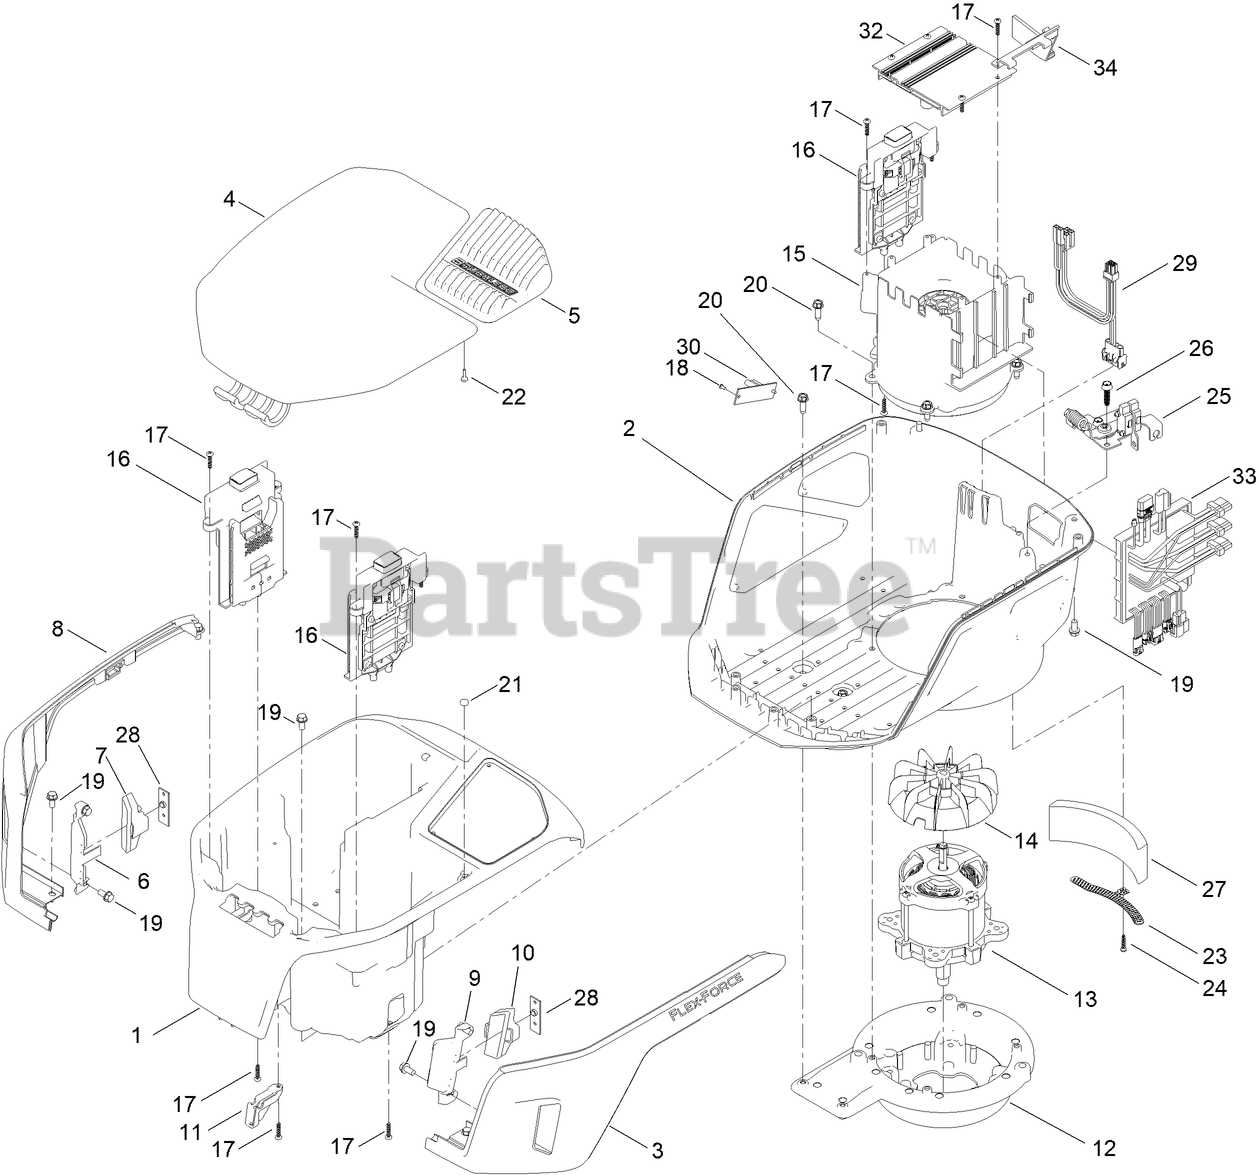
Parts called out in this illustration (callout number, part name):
1	BUCKET-BATTERY
2	SHROUD-LOWER
3	TRIM-SHROUD, LH
4	LID-MOTOR
5	HEATSINK-CONTROLLER
6	LENS-LED, RH
7	REFLECTOR-LED, RH
8	TRIM-SHROUD, RH
9	LENS-LED, LH
10	REFLECTOR-LED, LH
11	BRACKET-SUPPORT, LID
12	MOUNT-BASE, MOTOR
13	MOTOR-60V
14	FAN-MOTOR
15	SHROUD-MOTOR
16	RECEIVER-BATTERY
17	SCREW-PPH
18	SCREW-PPH
19	SCREW-PLASTITE
20	SCREW-HWHTF
21	MAGNET
22	SCREW-PPH
23	BRACKET-FOAM
24	SCREW-PLASTIC, PPH
25	BAIL SWITCH ASM
26	SCREW-FLANGE, PLASTIC
28	BOARD-LIGHT, LED
29	HARNESS-WIRE
30	DRIVER-LED
32	CONTROLLER-PMU
33	CONTROLLER-MOTOR
34	BRACKET-PMU
